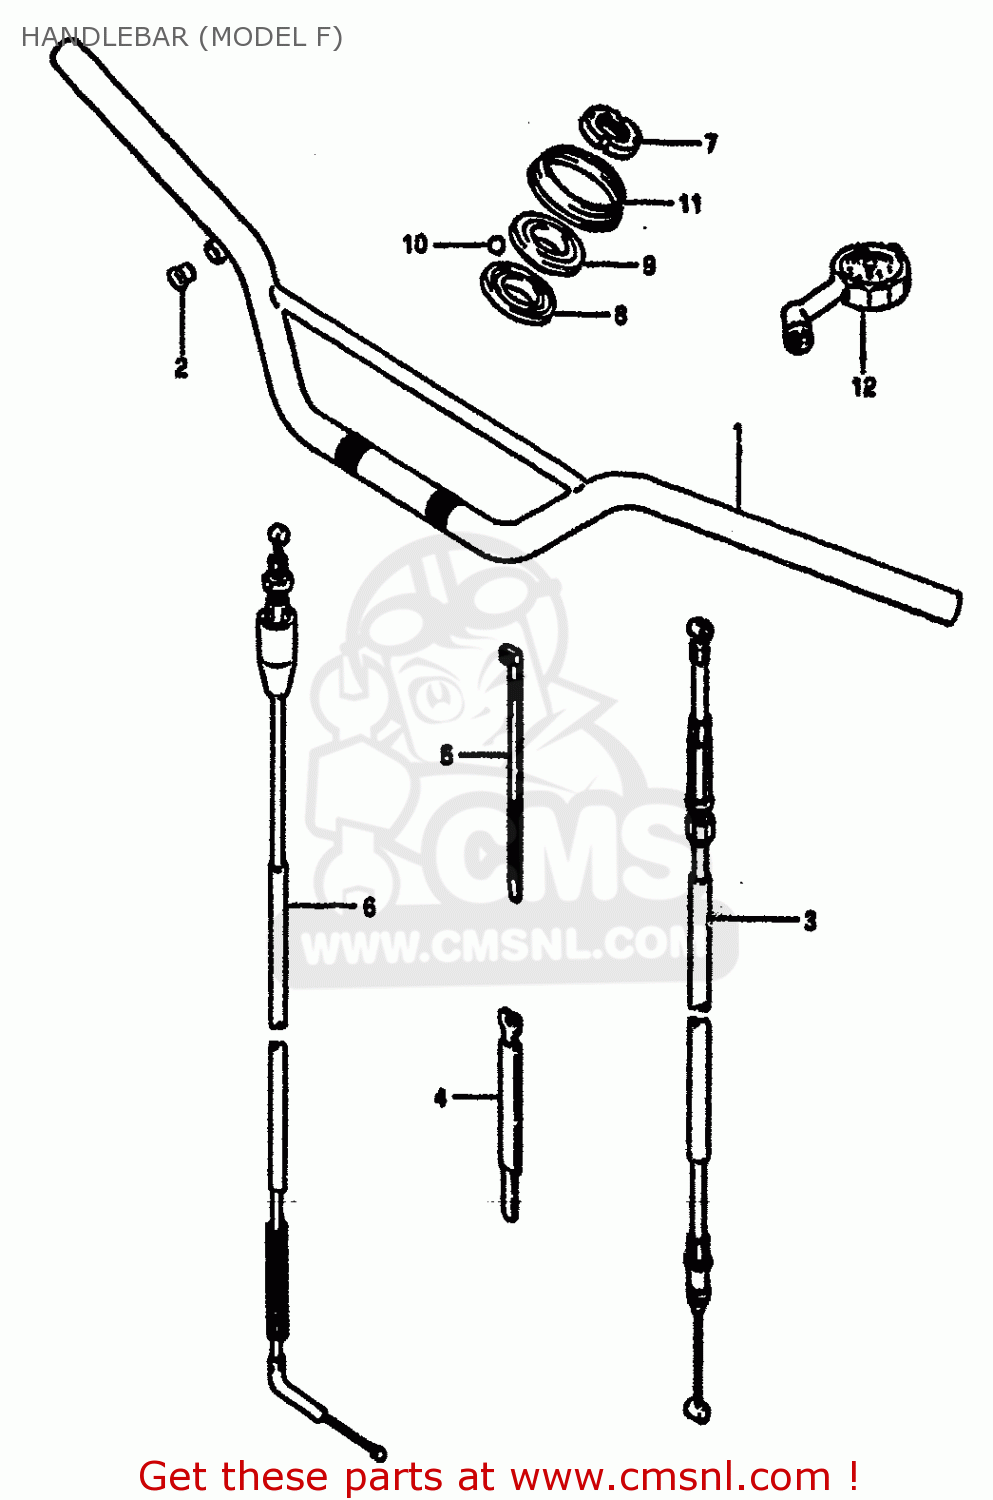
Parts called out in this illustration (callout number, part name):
1	HANDLEBAR
2	CAP(OD:14)
3	CABLE ASSY,CLUTCH
4	CLAMP(L:250)
5	CLAMP(L:235)
6	CABLE ASSEMBLY,THROTTLE
7	NUT,STEERING STEM
8	RACE,STEERING,INNER,UPPER
9	RACE,STEERING,OUTER,UPPER
10	BALL
11	SEAL,STEERING UPR DUST
12	GAUGE ASSY,AIR PRESSURE
